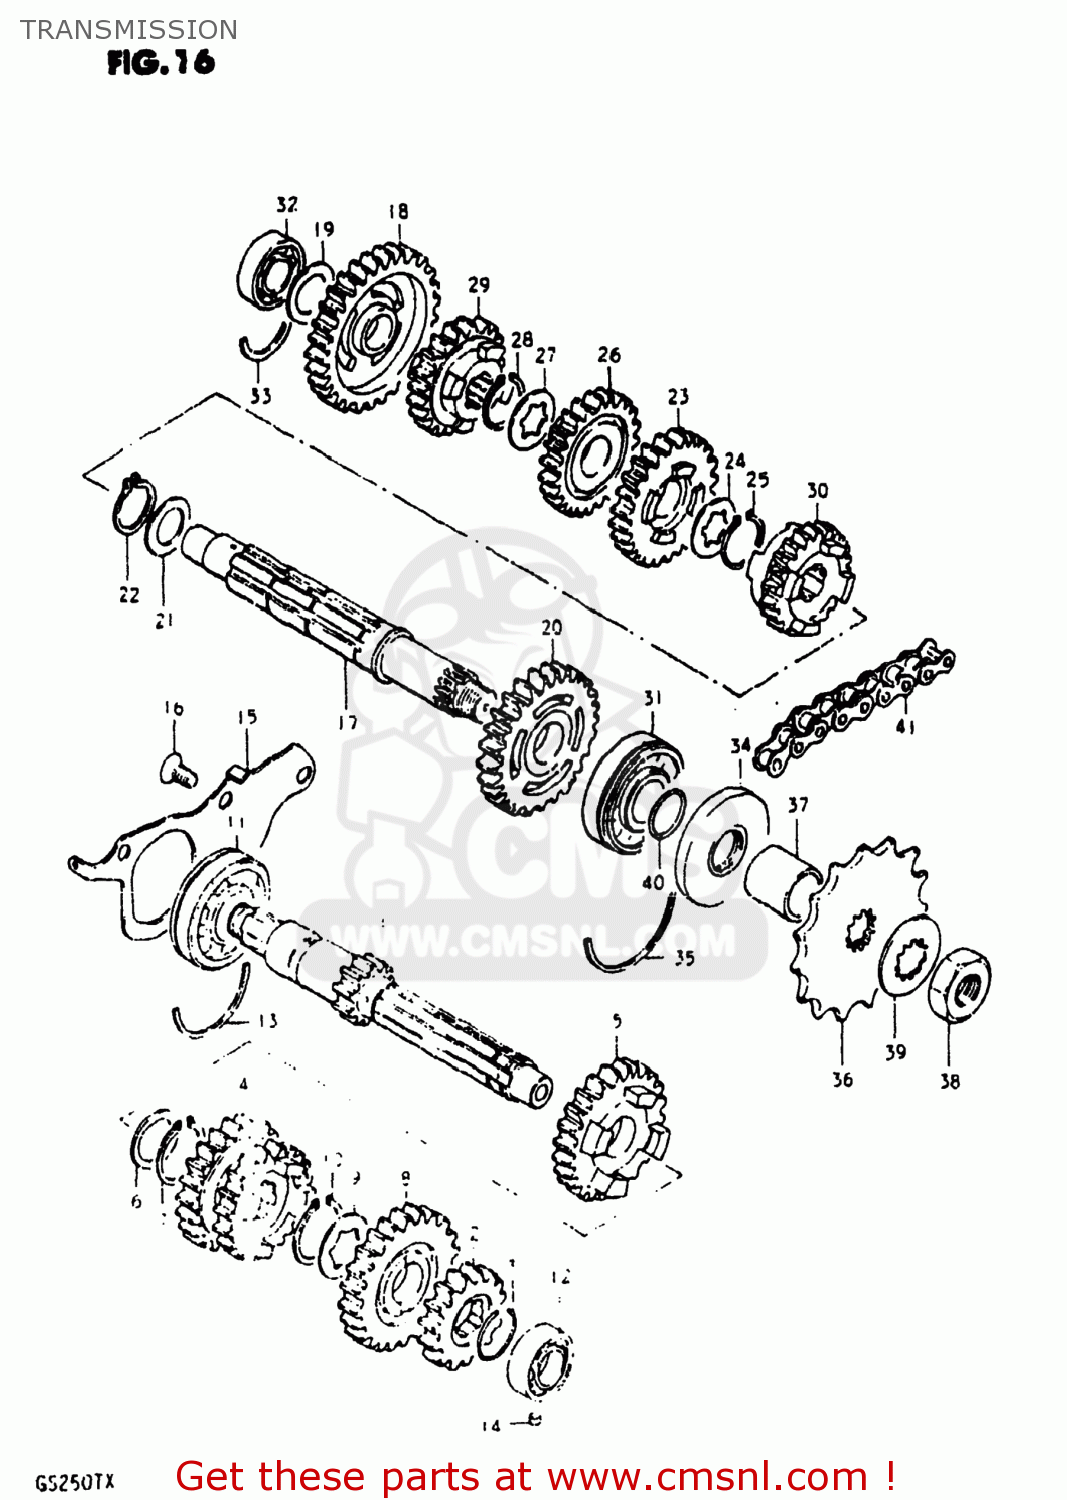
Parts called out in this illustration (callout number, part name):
1	SHAFT,COUNTER
2	GEAR,SECOND DRIVE
3	CIRCLIP
4	GEAR,THIRD/FOURTH DRIVE
5	GEAR,FIFTH DRIVE
6	SHIM
7	CIRCLIP
8	GEAR,SIXTH DRIVE
9	WASHER,LOCK
10	CIRCLIP
11	BEARING
12	ROLLER BEARING (17X31X1
13	C RING
14	PIN
15	RETAINER,BEARING
16	SCREW
17	SHAFT,DRIVE
18	GEAR,FIRST DRIVEN
19	WASHER,THRUST
20	GEAR,SECOND DRIVEN
21	SHIM
22	CIRCLIP
23	GEAR,THIRD DRIVEN
24	WASHER,LOCK
25	CIRCLIP
26	GEAR,FOURTH DRIVEN
27	WASHER,LOCK
28	CIRCLIP
29	GEAR,FIFTH DRIVEN
30	GEAR,SIXTH DRIVEN
31	BEARING
32	BEARING, RH
33	C RING
34	SEAL,OIL(25X52X11.5)
35	C RING
36	SPROCKET,ENGINE(NT:15)
37	SPACER
38	NUT
39	WASHER,LOCK
40	O RING(D:1,ID:19.5)
41	CHAIN ASSEMBLY,DRIVE
